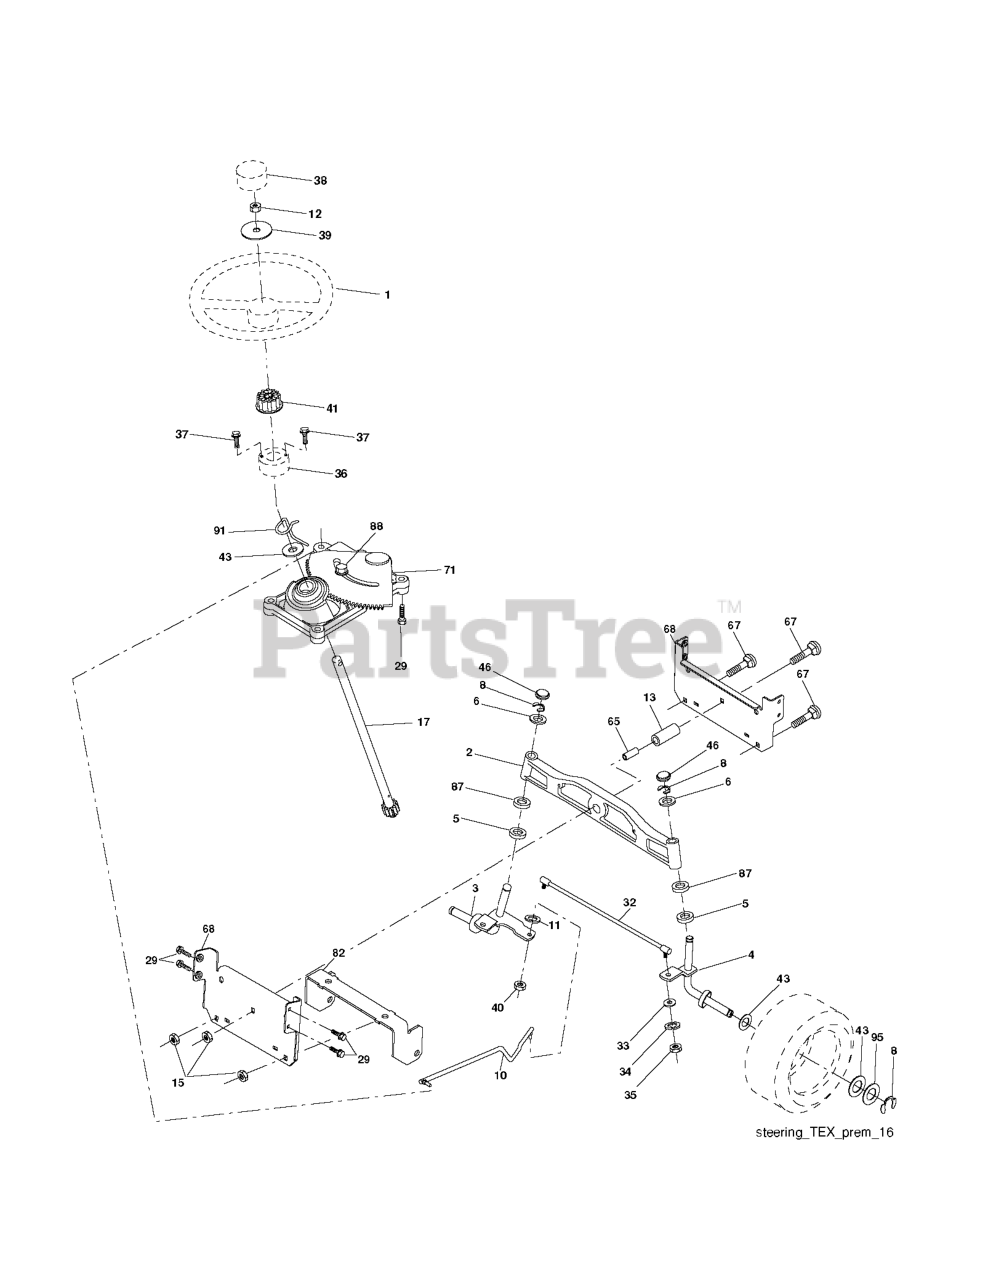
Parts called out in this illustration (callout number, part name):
1	STEERING WHEEL
2	AXLE ASSY FRONT
3	SPINDLE.ASM.LH.15"TIRES
4	SPINDLE.ASM.RH.15"TIRES
5	THRUST WASHER
10	DRAGLINK.15".TIRES.2001
11	WASHER, LOCK 3/8
12	NUT.HEX.1/2-20
13	TUBE, PIVOT AXLE
15	NUT
17	SHAFT ASM STRG
29	SCREW, 3/8-16X3/4
33	WASHER M
34	WASHER.LOCK.HVY.HLCL.SPR.5/16
35	NUT, CROWNLOCK
36	BUSHING, STRG. BLK
37	SCREW.TT.#10-32X.5.3/8.FLANGE
38	STEERING WHEEL
39	WASHER 9/16"ID, 2 3/8"OD
40	NUT CROWNLOCK 3/8-24
41	ADAPTER, WHEEL STNG..
46	CAP.SPINDLE.BLACK
65	SPACER BRACE AXLE
67	BOLT CARRIAGE
68	BRACE.AXLE.15"TIRES
71	STEERING ASM
82	BRACKET.SUSP.CHASSIS.FRONT.15
87	WASHER, FLAT .781 X 1 1/2"
88	BOLT, SHOULDER 7/16-20
91	CLIP.STEERING
95	WASHER.HARDENED
